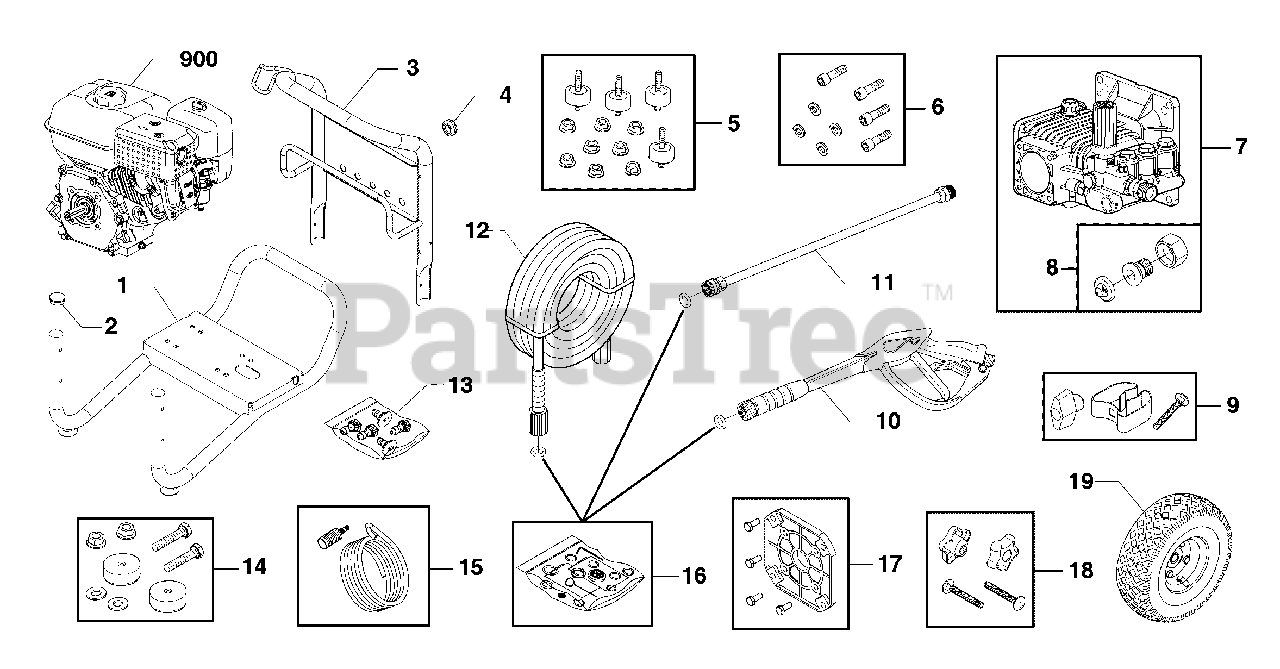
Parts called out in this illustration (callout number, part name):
1	BASE
5	KIT, Vibration Mount
6	KIT-HARDWARE PUMP MOUNTING
8	KIT, Connector, Hose, Garden
13	KIT-QC NOZZLES
14	KIT, Vibration Mount
15	KIT, Chem Hose & Filter
16	O-RING, 0.706 ID X 0.097
17	KIT - ENGINE FLANGE
18	KIT-HARDWARE, HANDLE
19	WHEEL
900	ENGINE, 208CC, BLACK RECOIL
